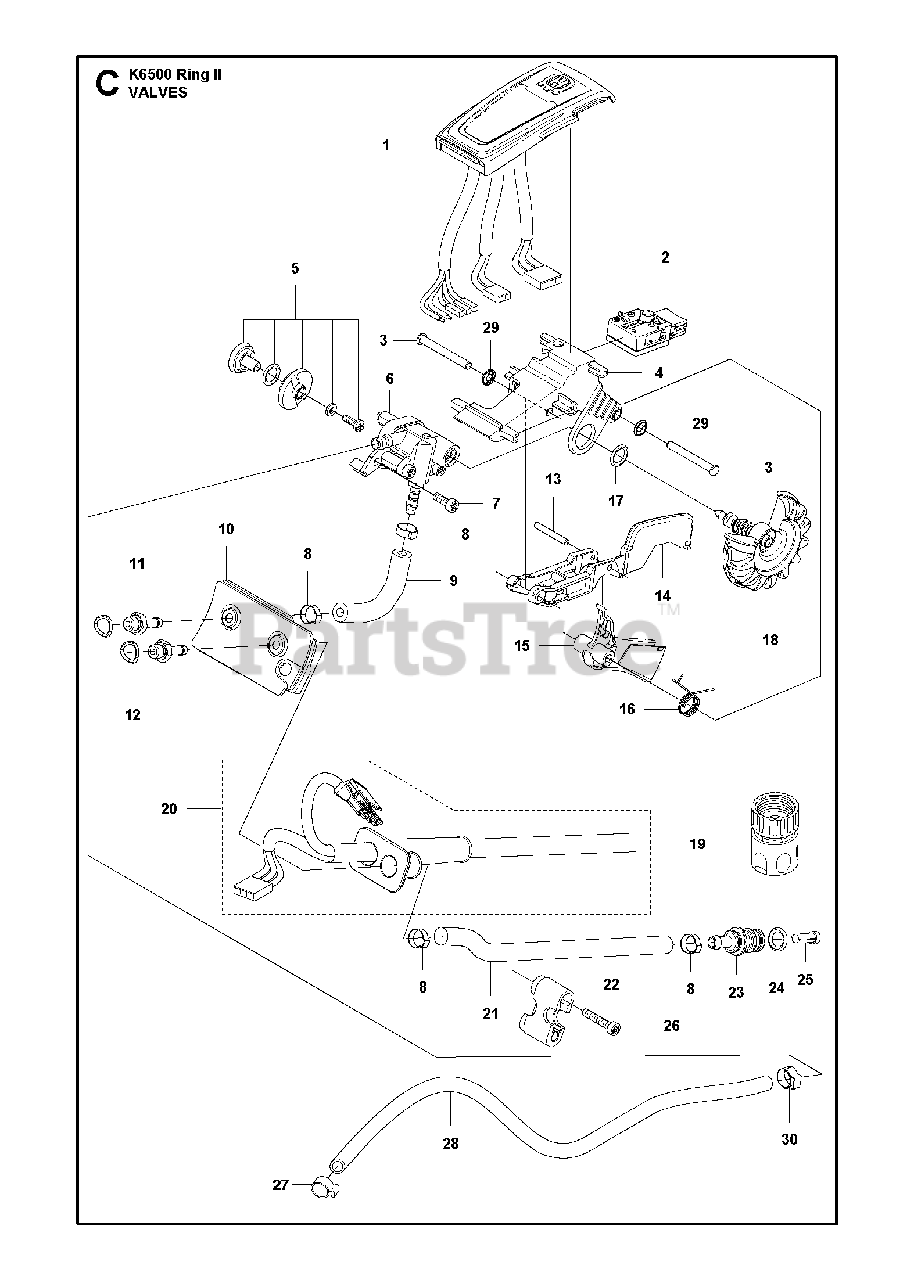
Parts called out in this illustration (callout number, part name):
7	SCREW ITXSCT
13	PARALLEL PIN
19	COUPLER"3/4"""
19	COUPLER"1/2"""
26	SCREW ITXSCT
27	HOSE CLAMP
